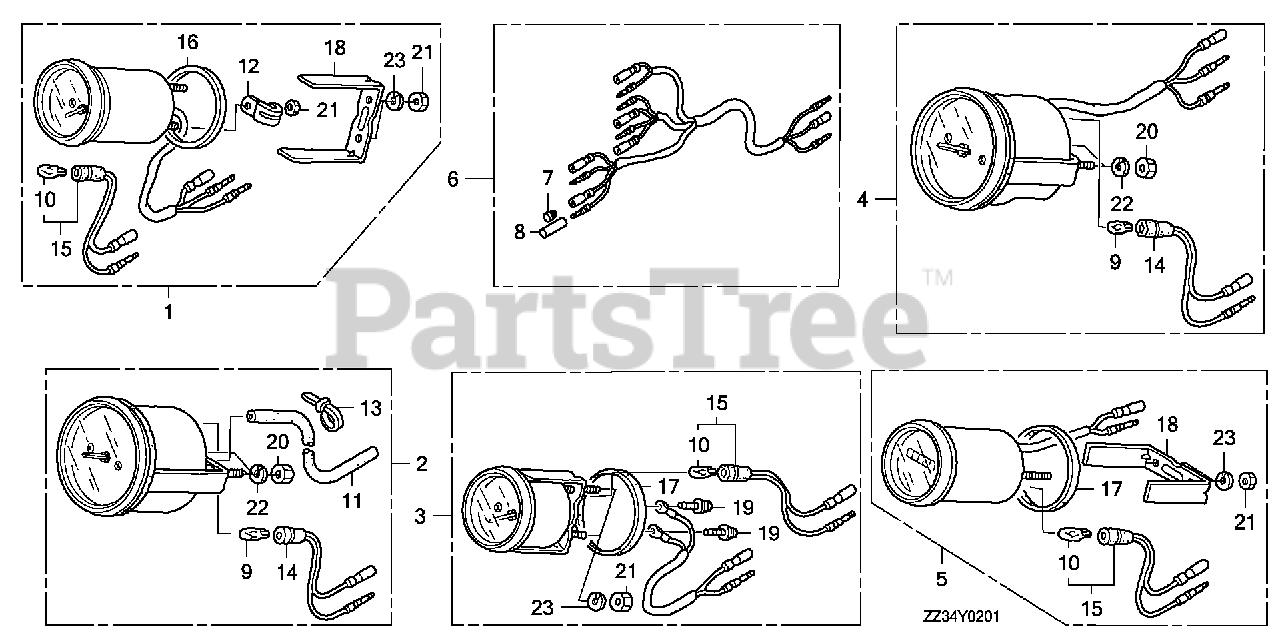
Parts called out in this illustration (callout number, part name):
1	METER KIT, TRIM
1	METER KIT, TRIM (B)
2	SPEEDOMETER KIT
2	SPEEDOMETER KIT (B)
3	METER KIT, VOLT
3	METER KIT, VOLT (B)
4	METER KIT, TACHO
4	METER KIT, TACHO (B)
5	METER KIT, HOUR (NA USE ALT:39700-ZW5-000ZA)
5	METER KIT, HOUR (B) (NA USE ALT:39700-ZW5-000ZA)
6	HARNESS ASSY., METER (B)
7	PLUG, CONNECTOR (INNER)
8	PLUG, CONNECTOR (OUTER)
9	BULB, WEDGE BASE (T10) (12V 1.7W) (STANLEY)
10	BULB, WEDGE BASE (12V 1.7W)
11	TUBE, SPEED METER (4X7X8000)
12	CLAMP
13	BAND, SELF-LOCK
14	SOCKET
15	SOCKET
16	GASKET
17	GASKET
18	BRACKET
19	SCREW-WASHER (3X22)
20	NUT, HEX. (5MM)
21	NUT, HEX. (4MM)
22	WASHER, SPRING (5MM)
23	WASHER, SPRING (4MM)
